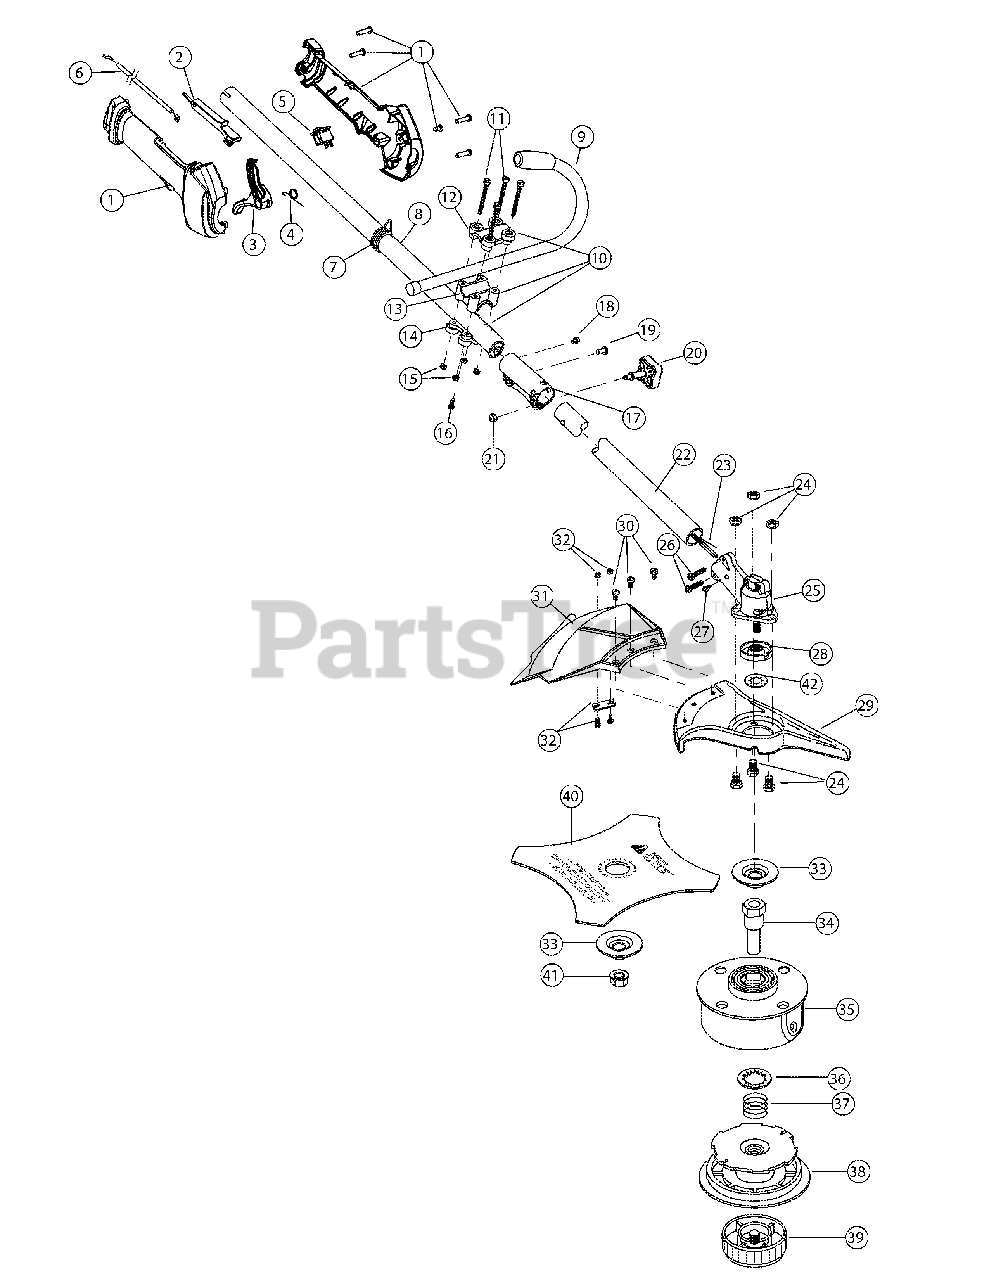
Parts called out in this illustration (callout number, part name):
1	Throttle Housing Assembly
2	Throttle Trigger Lock-Out
3	Throttle Trigger
4	Throttle Trigger Spring
5	Switch Assembly
6	Throttle Cable
7	Harness Clip
8	Upper Drive Shaft Housing Assembly
9	J-Handle Assembly
10	Handle Bracket Assembly
12	Upper Handle Clamp
13	Middle Handle Clamp
14	Lower Handle Clamp
16	Anti-Rotation Screw
17	Split Boom Coupler
20	Adjustment Knob
21	Knob Retaining Nut
22	Lower Drive Shaft Housing Assembly
23	Lower Flexible Drive Shaft
24	Shield Mount Screw Assembly
25	2 piece Gearbox Assembly
26	Gearbox Mounting Hardware
27	Anti-Rotation Screw
28	Blade Driver
29	Blade Shield/Shield Mount
30	Shield Mounting Screw
31	Shield and Blade Assembly
32	Blade Assembly
33	Retaining Washer
34	Spool Shaft
35	Outer Spool Assembly
36	Retainer
39	Bump Head Knob Assembly
40	4-Tooth Blade
